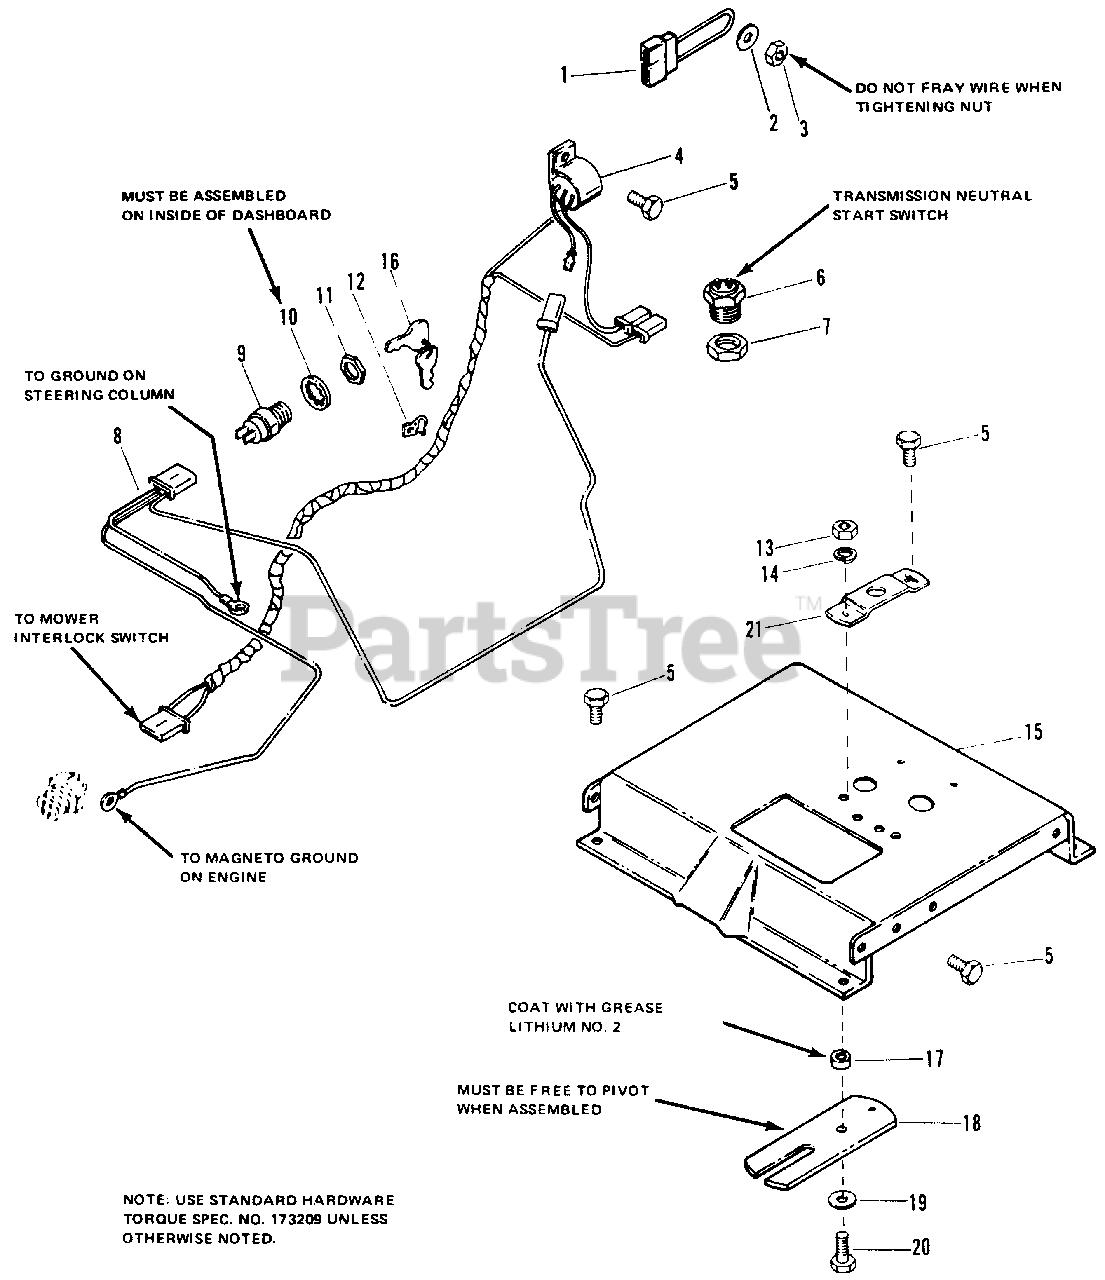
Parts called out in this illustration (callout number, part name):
1	WIRE ASSEMBLY
2	WASHER, Cup
3	NUT, Hex, full lock, 5/16-18
4	IGNITION INTERLOCK
5	SCREW, Taptite, 1/4-20 x 3/8
6	SWITCH, Interlock
7	NUT, Pal, 9/16-18
8	HARNESS, Wire
9	SWITCH, Manual Start
10	LOCKWASHER, Int., 5/8
11	NUT, Special, 5/8-32
13	NUT, Hex, 5/16-18
14	LOCKWASHER, 5/16
15	SUPPORT, Frame
16	KEYS, (Set of 2)
18	LEVER, Switch
20	CAPSCREW, Hex, 5/16-18 x 1
21	BRACKET, Switch
